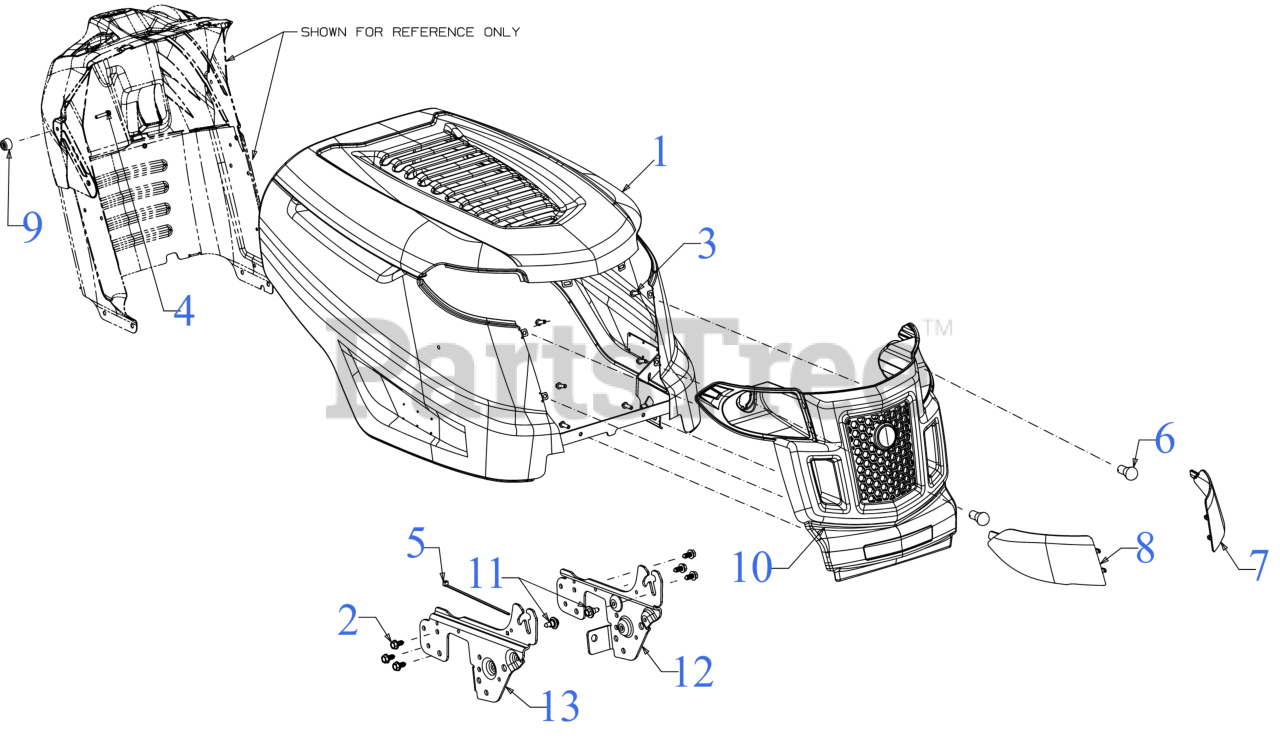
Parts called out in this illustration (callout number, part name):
2	SCREW 5/16-18 x .750
3	SCREW 1/4 x .750
4	SCREW #12 x 1.15
5	7" CABLE TIE
6	MINIATURE LAMP-12V #1156
7	LENS (LH)
8	LENS (RH)
9	DASH BUMPER K STYLE
10	GRILLE(K STYLE) NON T-BILT
11	SHOULDER SCREW .43X.29X5/16-18 TT
